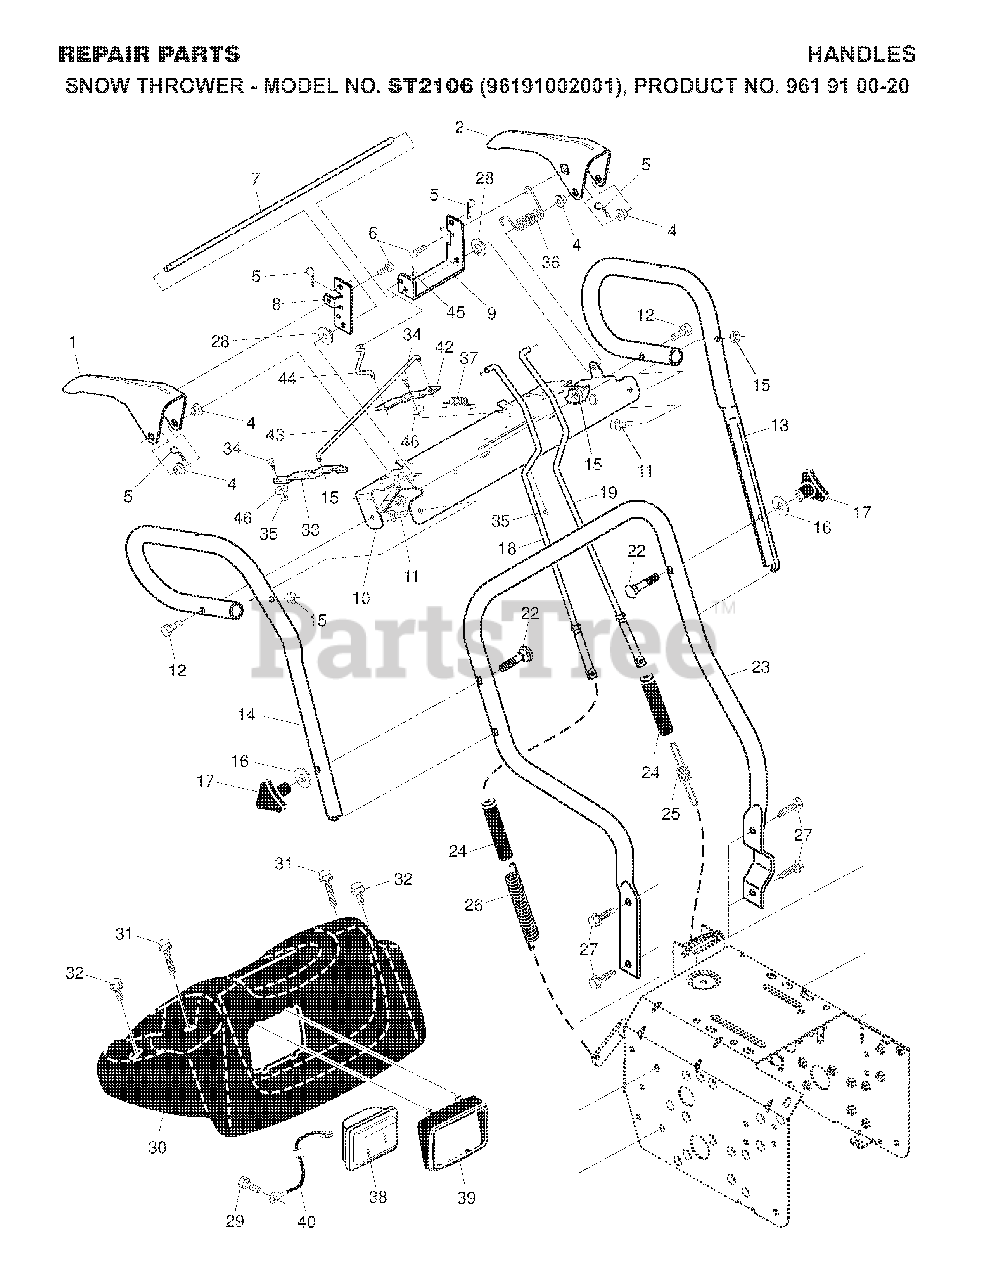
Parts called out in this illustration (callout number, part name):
1	LEVER, AUGER CONTROL, RH
2	LEVER, TRACTION DRIVE CONTROL,
4	BUSHING, FLANGE
5	SPRING RETAINER
7	ROD.INTERLOCK
8	ARM,IMPELLER ROD
9	ARM,TRACTION ROD
10	PANEL.CONTROL
11	HEX BOLT
13	TUBE.HANDLE.LOOP.LH.BLACK
14	TUBE.HANDLE.LOOP.RH.BLACK
15	NUT, LOCK 5/16-18
17	KNOB.HANDLE.3/8.TRI-POINT.BLAC
18	ROD.ASM.IMPELLER
19	ROD.ASM.TRACTION.
22	BOLT 3/8-16 X 2-1/4
23	TUBE.LOWER.HANDLE.24.BLACK
24	SLEEVE, SPRING
25	SPRING, TRACTION DRIVE
26	SPRING, AUGER CONTROL
27	SCREW 3/8-16X1
28	SPACER CONTROL LEVER
30	PANEL.CONSOLE.HEADLIGHTS
31	SCREW, HEX HD TAPPING #10-24 1
32	SCREW, HEX HEAD, TAPPING
33	LATCH.INTERLOCK
34	BOLT SHOULDER
35	NUT **
36	RP SPRING, TORSION
37	SPRING LATCH
38	HEADLIGHT, HALOGEN
39	BEZEL.HEADLIGHT.BLACK
40	HARNESS.WIRE.HALOGEN
42	LEVER.INTERLOCK
43	ROD.LATCH.INTERLOCK
44	ROD.ASM INTERLOCK
45	RETAINER CLIP
46	THRUST WASHER
